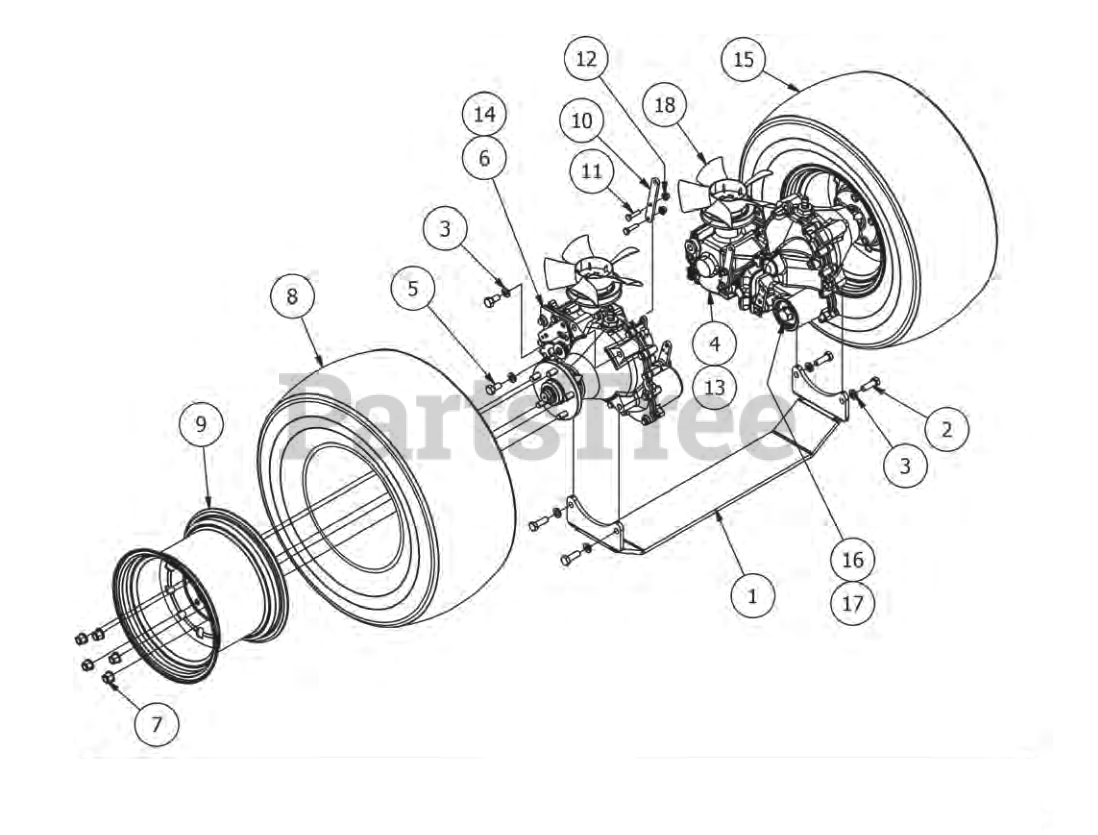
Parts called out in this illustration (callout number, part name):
1	Outlaw Transaxle Cross Brace
2	1/2" x 1 1/2" Hex Bolt
3	1/2" Lock Washer
4	ZT-5400-Left
5	1/2" x 1" Hex Bolt
6	ZT-5400-Right
7	Acorn Lug Nut
8	24 x 12.00-10 outlaw Tire
9	10" Black Wheel For Outlaw
10	2015 Outlaw Brake Adapter (4400 Transaxles Only)
11	5/16 x 1 1/4 Hex Bolt (4400 Transaxles Only)
12	5/16" Flange Nut Zinc W/Serrations (4400 Transaxles Only)
13	4400 Transaxle Left (Base Outlaw)
14	4400 Transaxle - Right (Base Outlaw)
15	24 x 12.00-10 Tire and Black Wheel Assembly
16	Hydro Filter for Outlaw Extreme
17	4400 Hydro Filter for Outlaw
18	Fan/Pulley Kit for Oulaw
